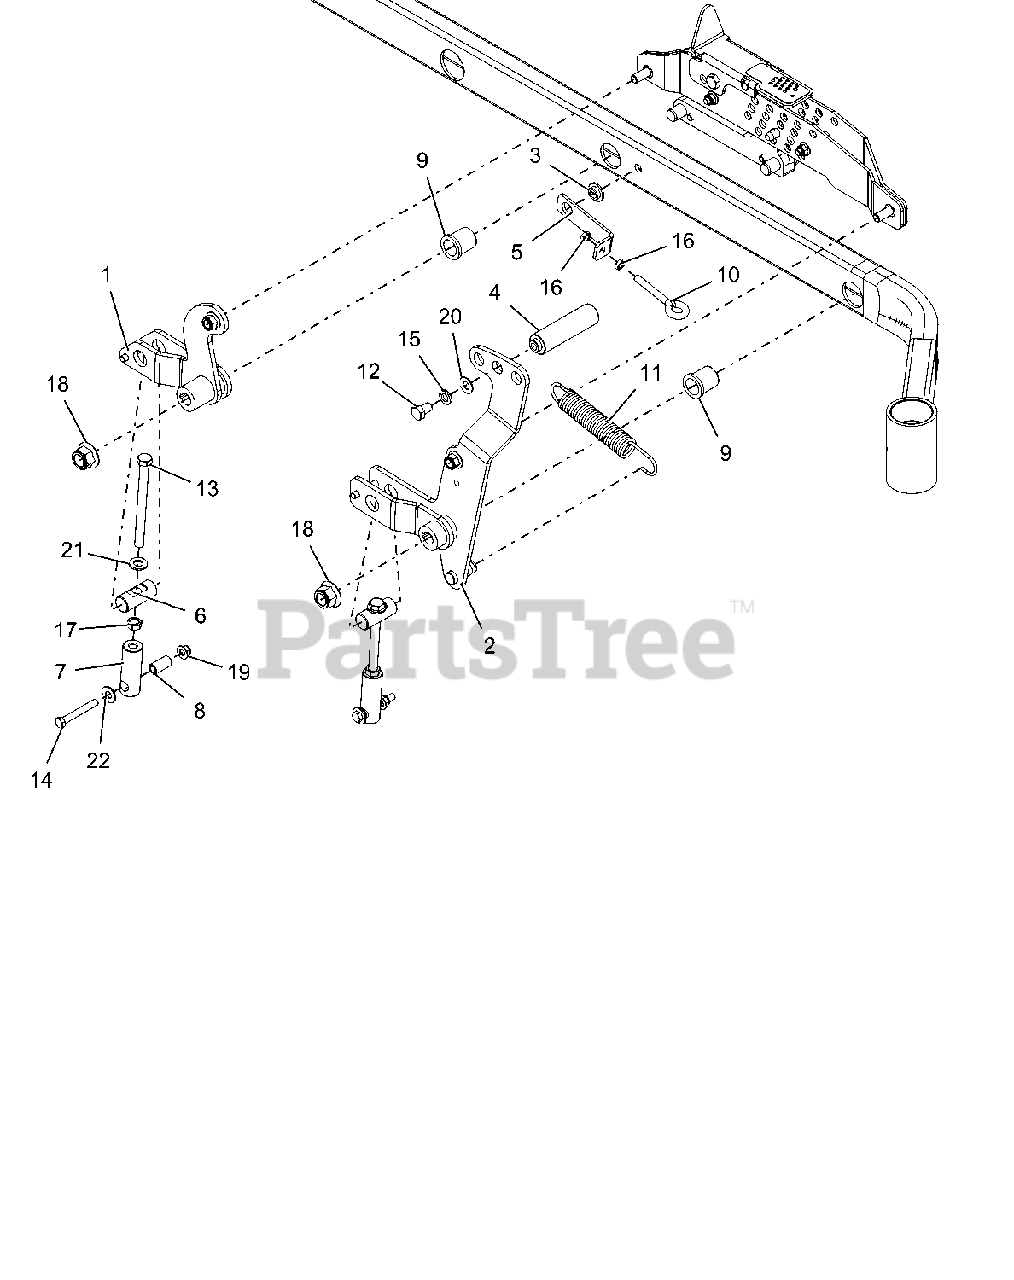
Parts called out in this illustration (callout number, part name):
1	WLDMT, REAR RH DECK LIFT ARM (BLACK)
2	WLDMT, FRONT RH DECK LIFT ARM (BLACK)
3	BSHG, FLANGE .515X.750X.31X1.12
4	PEDAL, LIFT
5	BRKT, SPRING ANCHOR (RED)
6	PIN, DECK LIFT
7	LINK, DECK LEVELING
8	SPCR, DECK LEVELING
9	BSHG-FLG 1.00X1.25X1.5X1.5
10	BOLT, EYE .375-16
11	SPRG, TENSION .162 X 1.250 X 8.250
12	BLT-HEX .50-13X.75 GR5 YWZC
13	BLT-HEX .50-13X6.00 2.5 THD GR5 YWZC
14	BLT-HEX .38-16X2.75 GR8 YWZC
15	WSHR-LK .50X.125 REG YWZC
16	NUT, JAM .375-16 YWZC
17	NUT, JAM .500-13 YWZC
18	NUT-LK-NYL-FLG .75-10 YWZC
19	NUT-LK-NYL-FLG .38-16 YWZC
20	WSHR-FL-STL .505X1.00X.062 YWZC
21	WSHR-FL-STL .557X1.040X.102 YWZC HARD
22	WSHR-FL-STL.438X1.00X.083 YWZC
